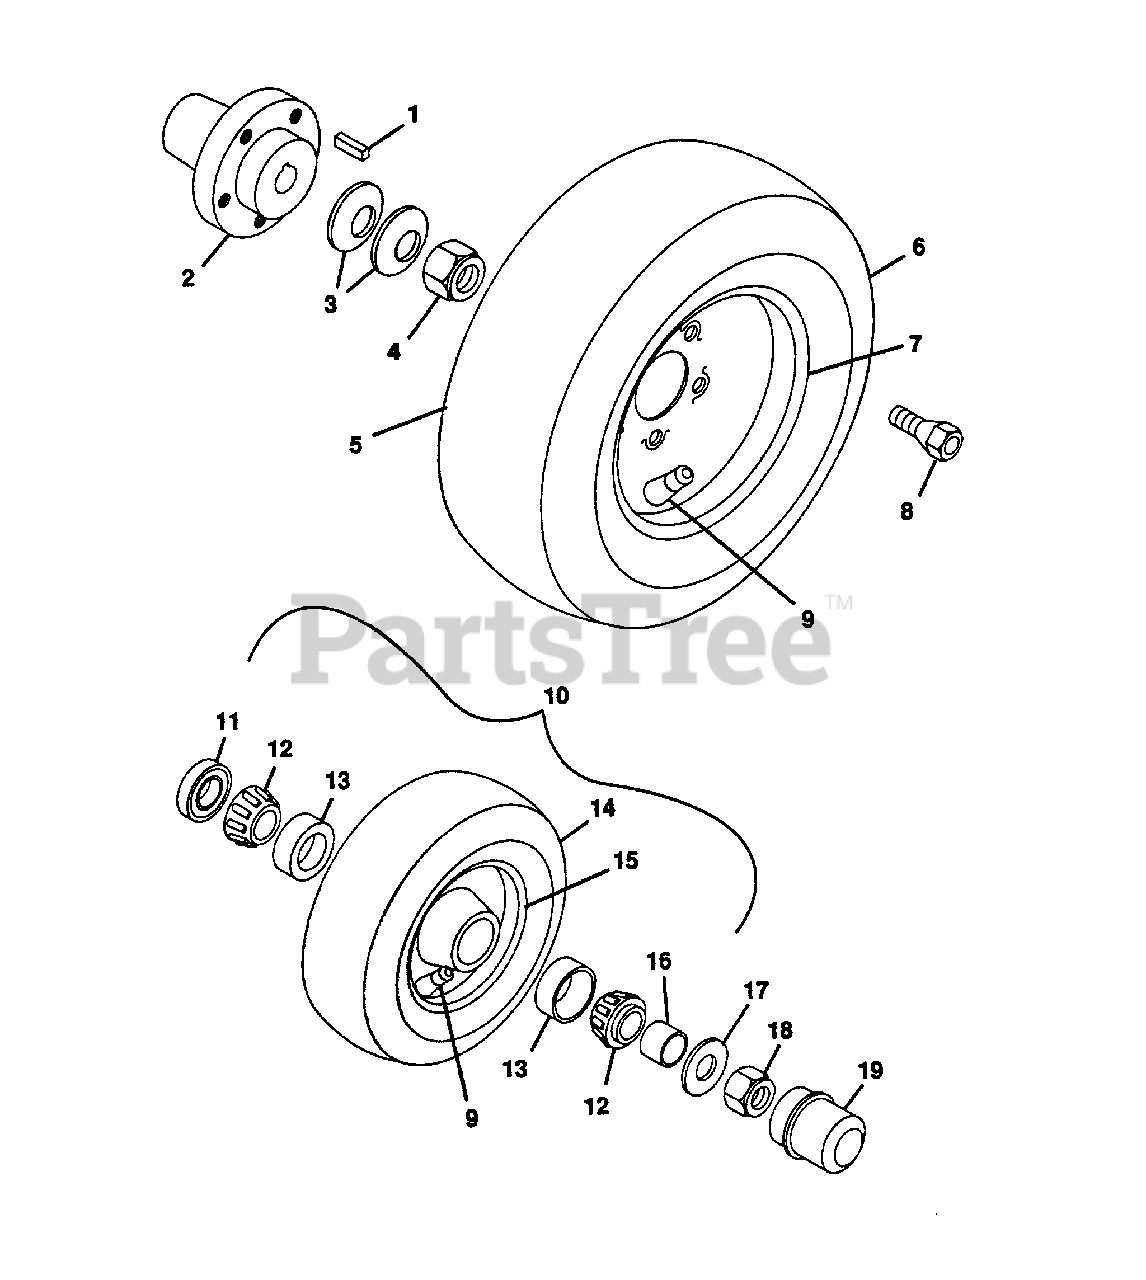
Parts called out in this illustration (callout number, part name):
1	Key, Square .312x2.25
2	Hub, Wheel
3	Spring, Belleville
4	Nut, Lock 1-14
5	Assembly, Wheel 23x8.50-12
6	Tire, Rear 23x8.50-12
7	Weldment, Rim Rear
8	Bolt, Hub 7/16-20x.75 Special
9	Assembly, Valve Stem
10	Assembly, Front Wheel 16x6.50-8
11	Seal, Oil
12	Bearing, Cone LM 11949
13	Bearing, Cup LM 11910
14	Tire, Front 16x6.50-8
15	Weldment, Rim Front
16	Spacer
17	Washer, Flat .656x1.312x.095
18	Nut, Lock 5/8-11
19	Cap, Dust
